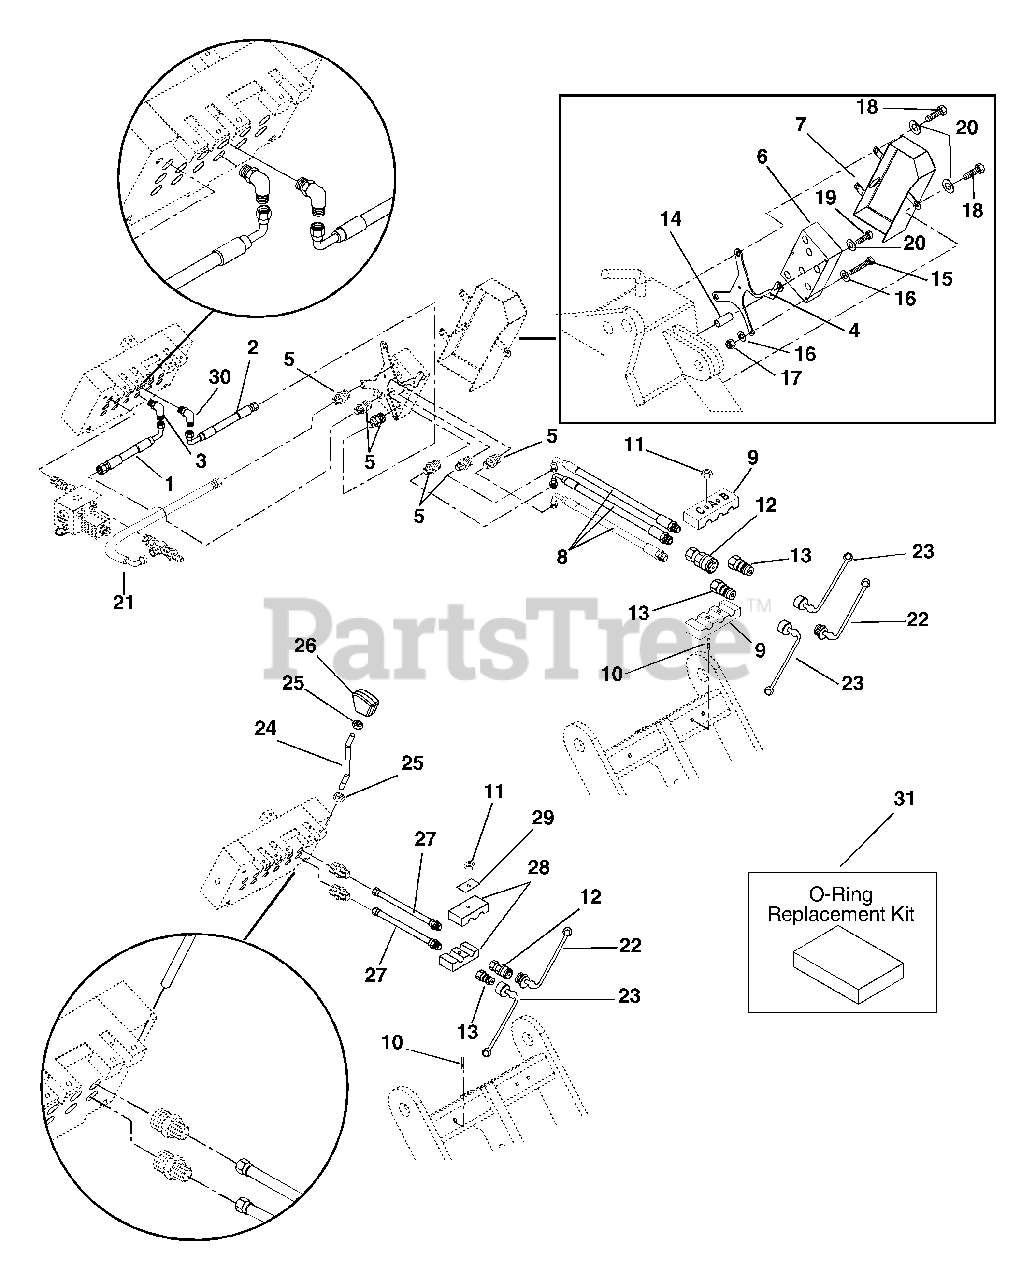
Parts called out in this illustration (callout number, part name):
1	Hose, Auxiliary To Trencher Valve
2	Hose, Auxiliary To Trencher Valve
3	Fitting, Hydraulic Elbow
4	Bracket-Trencher Valve
5	Adapter, Face Seal 8 x 8 1/2 O-Ring
6	Valve-Trencher Control
7	Guard-Heat
8	Hose, Hydraulic Trencher Valve
9	Clamp-Hydraulic .500 I.D. 3 Hose
10	Stud, M8-1.25 x 3.62"
11	Nut-Locking-Nylon M8-1.25
12	Coupling, Female Quick
13	Coupling, Male Quick
14	Spacer .344 x .750 x 1.500
15	Bolt-Hex M6-1x65
16	Washer-Flat-Steel .281 x .62 x .065
17	Nut-Locking-Nylon M6-1
18	Bolt-Hex M8-1.25 x 20
19	Bolt-Hex M8-1.25 x 65
20	Washer-Flat-Steel .344 x .688 x .065
21	Hose, Trencher Valve Return
22	Plug-Dust
23	Cap-Dust
24	Lever, 4 N 1 Bucket Control
25	Nut, Jam M8-1.25
26	Knob, Control
27	Hose, Hydraulic 4 N 1 Bucket
28	Clamp-Dual Hose .500 I.D. Hose
29	Plate-Cover
30	Fitting, Hydraulic Elbow
31	(Assorted O-Rings for Hydraulic Components to fittings) SAE
31	(Assorted O-Rings for Flat Face Seal Fittings and Hoses)
